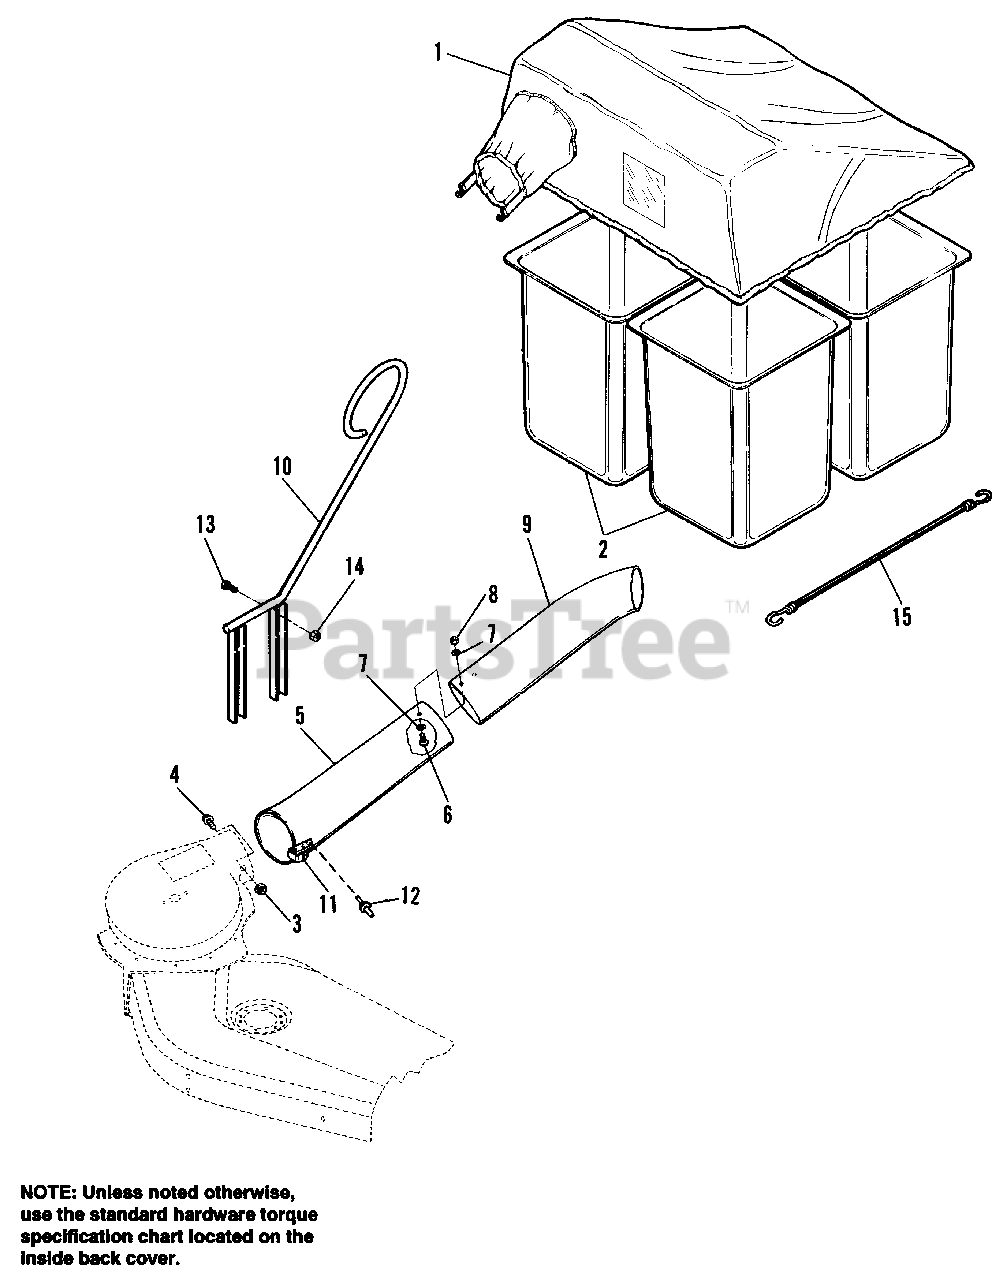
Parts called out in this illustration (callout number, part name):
2	BASKET, Grass Collector
3	NUT, Hex, Flange, Lock, 1/4-20
4	CARRIAGE BOLT, 1/4-20 x 5/8
5	TUBE ASSY., Lower (For 44" Mower Deck) (Incl. Ref. Nos.11 & 12)
5	TUBE ASSY., Lower (For 50" Mower Deck) (Incl. Ref. Nos.11 & 12)
6	SCREW, Truss Hd., #10-32 x 1/2
7	WASHER, Plain, #10
8	NUT, Hex, Washer Assy., #10-32
9	TUBE, Upper
10	SUPPORT, Tube
11	CLIP, Spring
13	CAPSCREW, Hex, 1/4-20 x 5/8
14	NUT, Hex, Lock, Esna, 1/4-20
